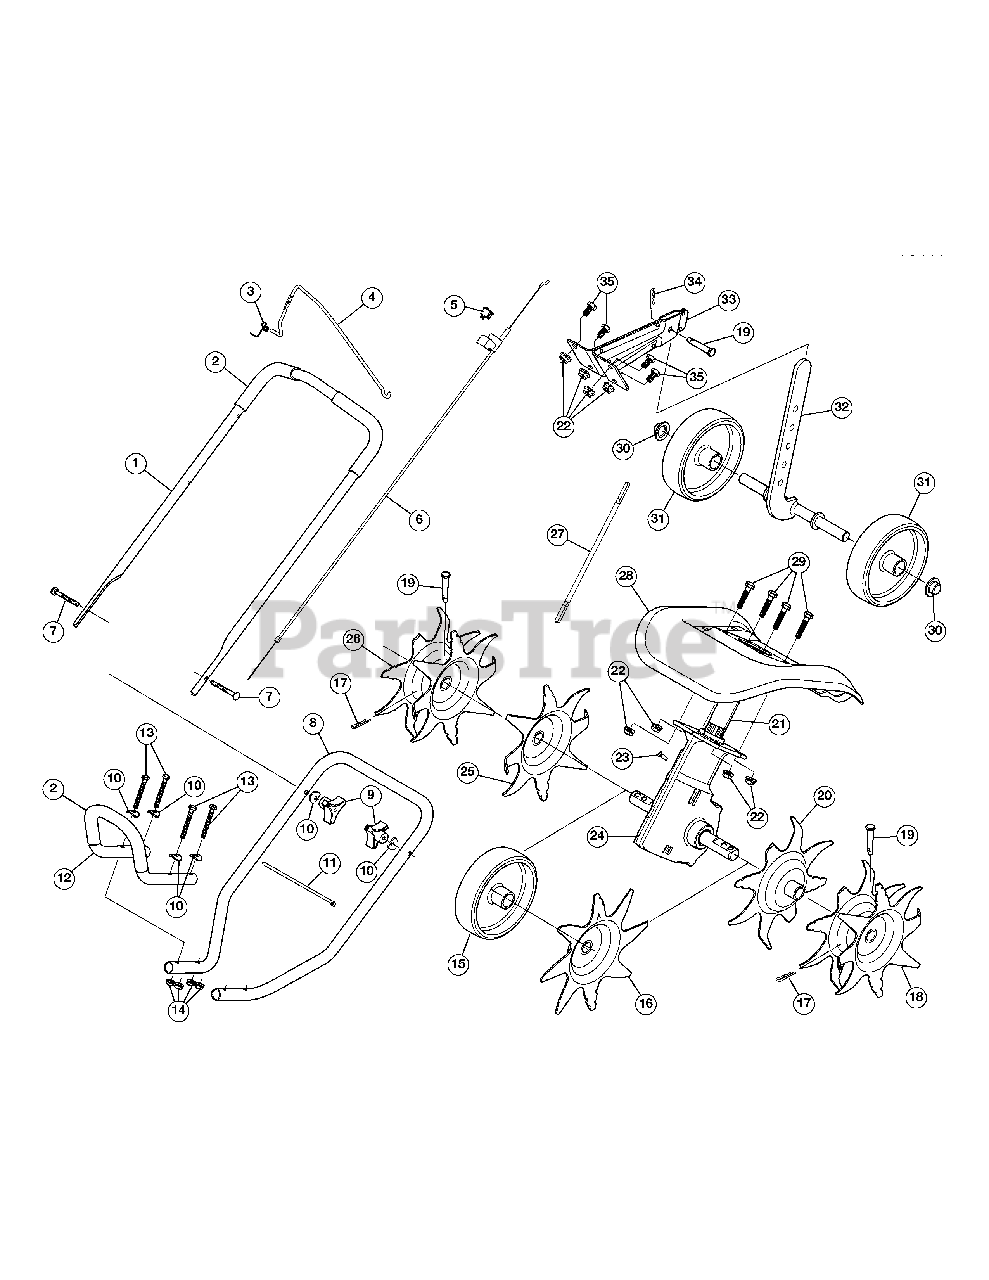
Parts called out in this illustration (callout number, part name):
1	Upper Handle
2	Foam Grip
3	Torsion Spring
4	Throttle Control
5	On/Off Switch
6	Throttle Cable
10	Washer
11	Cable Tie
12	Front Handle
15	Edger Wheel
16	Edger Tine
18	Tine (Left Outer)
19	Clevis Pin
20	Tine (Left Inner)
21	Drive Shaft Housing
23	Sleeve Retaining Bolt
24	Gear Box Assembly
25	Tine (Right Inner)
26	Tine (Right Outer)
27	Flex Shaft
28	Tine Shield
32	Wheel Support Bracket Assembly
33	Tailpiece Bracket Assembly
34	Cotter Pin
35	Cap Screw
